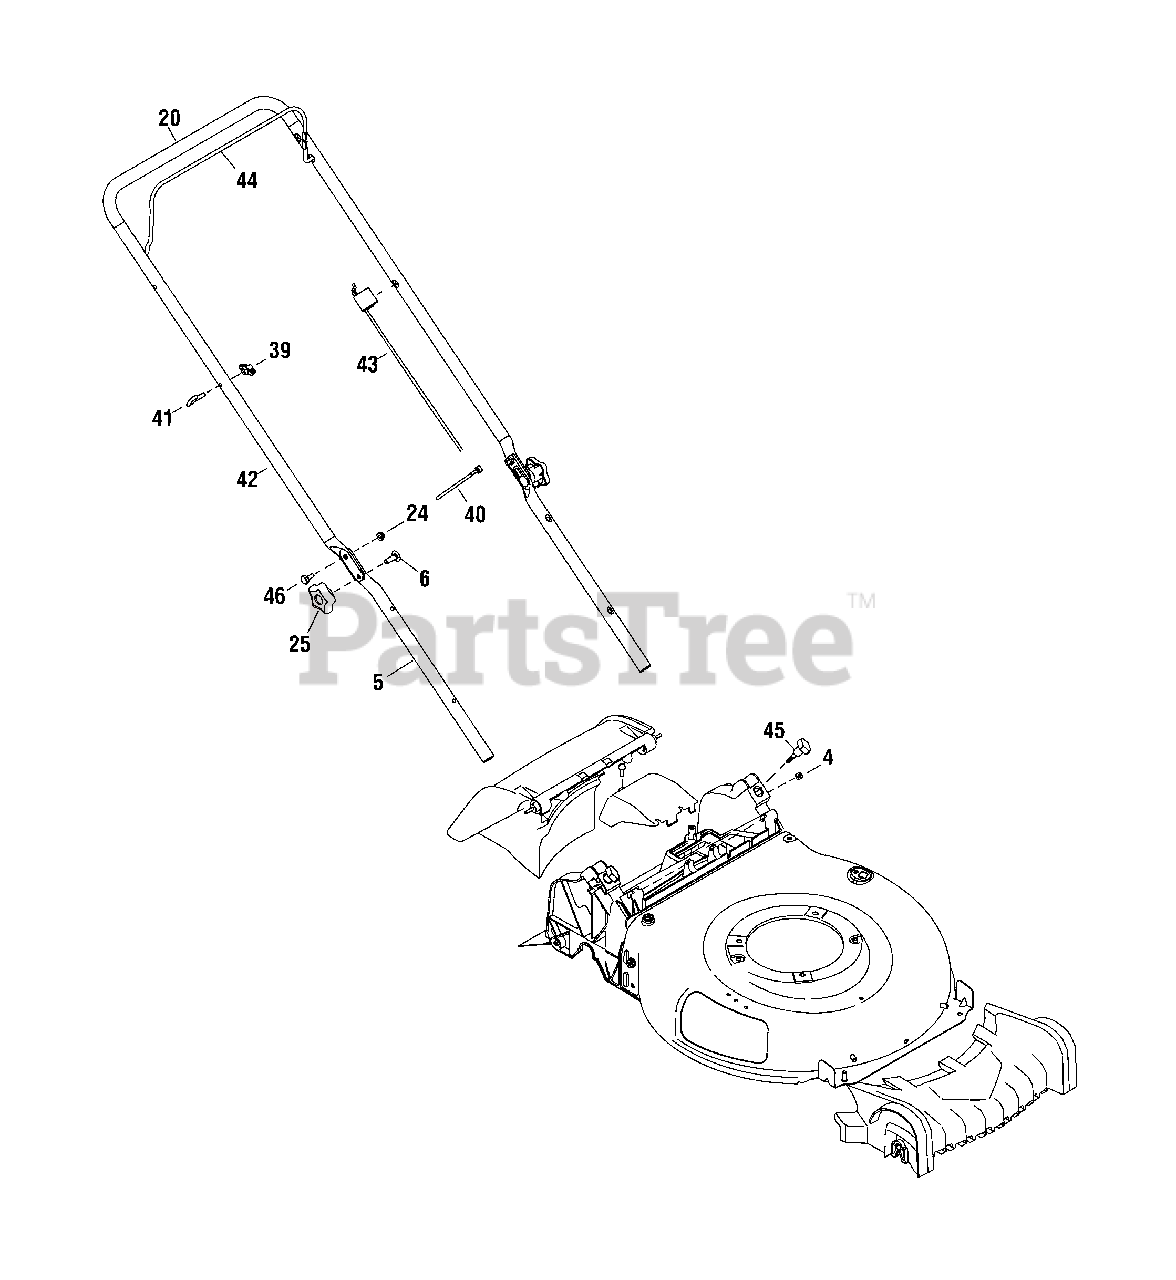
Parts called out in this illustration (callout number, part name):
4	NUT, Square, 1/4-20
5	HANDLE, Lower
6	BOLT, Carriage, 5/16-18 x 1, GR5
20	GRIP, Foam
24	NUT, Nylock Flanged, 1/4-20
25	KNOB, Wing, 5/16-18
39	KNOB, 1/4-20
40	TIE, Self Lock
41	GUIDE, Rope
42	HANDLE, Upper
43	CABLE, OPC Engine Brake
44	BAIL, Blade Control
45	NUT, Wing
46	BOLT, Shoulder, 1/4-20
